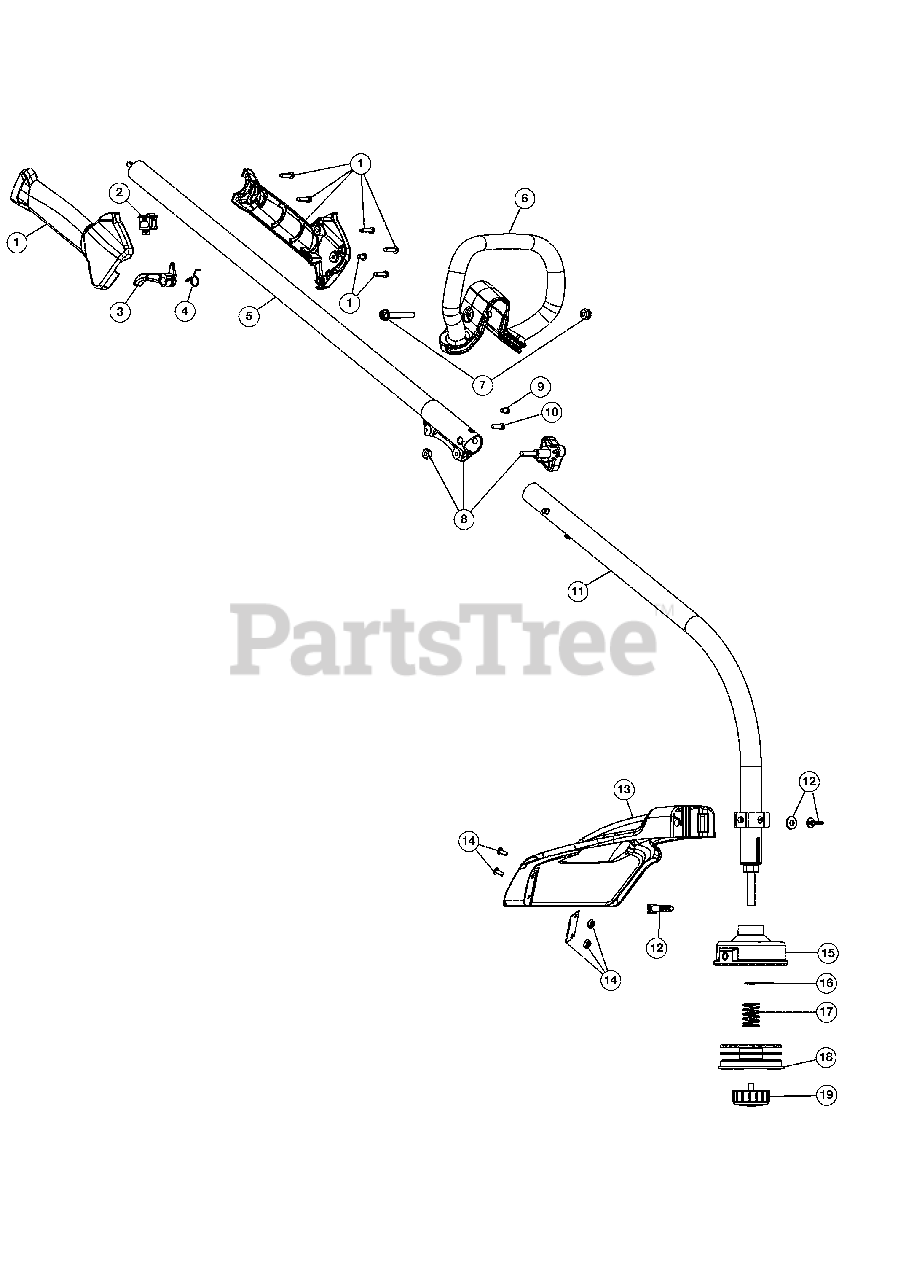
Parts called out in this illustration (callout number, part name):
1	Throttle Housing Assembly (Incl. 2-4)
3	Throttle Trigger
4	Throttle Trigger Spring
5	Upper Shaft Housing Assembly
6	D-Handle (Incl. 7)
7	D-Handle Bolt
8	Split Boom Coupler (Incl. 9-10)
9	Anti-Rotation Screw
11	Lower Shaft Housing Assembly
12	Shield Mounting Hardware
13	Shield Assembly (Incl. 14)
14	Blade Assembly
15	Outer Spool Assembly (Incl. 16)
16	Retainer
18	Inner Reel
19	Bump Head Knob Assembly
